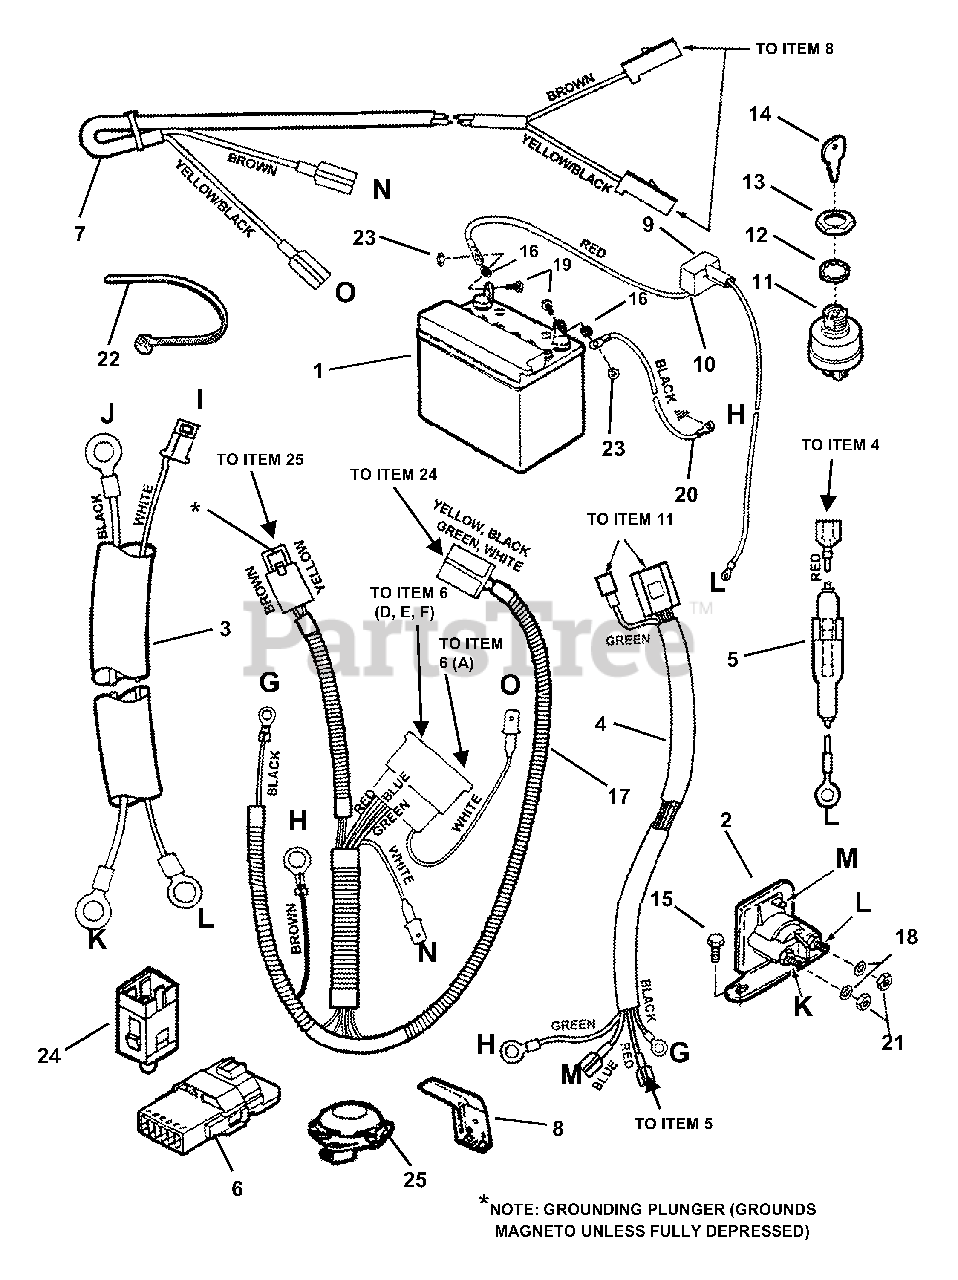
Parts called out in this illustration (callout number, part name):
1	KIT, Battery, 12V, U-1-7RS, 220CCA Dry Charge Snapper No Spill
2	SOLENOID
3	HARNESS, Starter Wiring (Briggs)
4	HARNESS, Ignition Wiring (Briggs)
5	HOLDER, Fuse
6	INTERLOCK Module (Briggs)
7	HARNESS, Deck Interlock Wiring
8	SWITCH, Deck Interlock (Normally Open)
9	COVER, Battery Cable
10	CABLE, Positive (Red) (17" Long)
11	SWITCH, Ignition (Indak #3G463A)
12	WASHER, 5/8" Internal Tooth Lock
13	NUT, 5/8-32 Hex
14	KEY, Switch
15	SCREW, 1/4-20 x 1/2" Hex Washer Self-Tap
16	RETAINER, 1/4" Bolt
17	HARNESS WIRE (Operator Presence Control) (Briggs)
18	WASHER, 1/4 Internal Tooth Lock
19	SCREW, 1/4-20 x 5/8" Hex Head Cap, Grade 5
20	CABLE, Negative (15" Long)
21	NUT, 1/4-20 Hex Grade 5 or B
22	TIE, 7" Long Cable
23	NUT, 1/4-20 Hex Center Lock, Grade 5 or B
24	SWITCH, Operator Presence Control (OPC) Traction (NO/NC)
25	SWITCH, Seat (Normally Closed)
